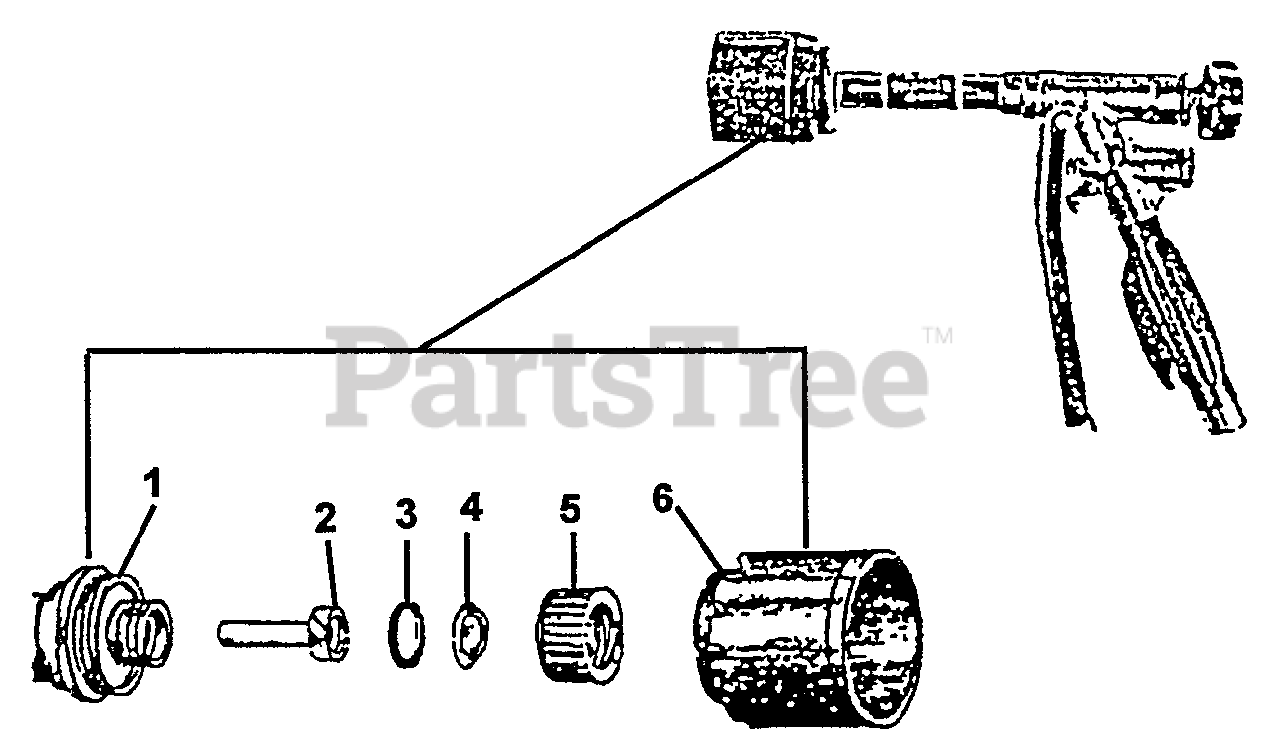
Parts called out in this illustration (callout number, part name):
1	NOZZLE BODY
2	CORE, ZOOM
4	PLATE, NOZZLE
5	CAP
